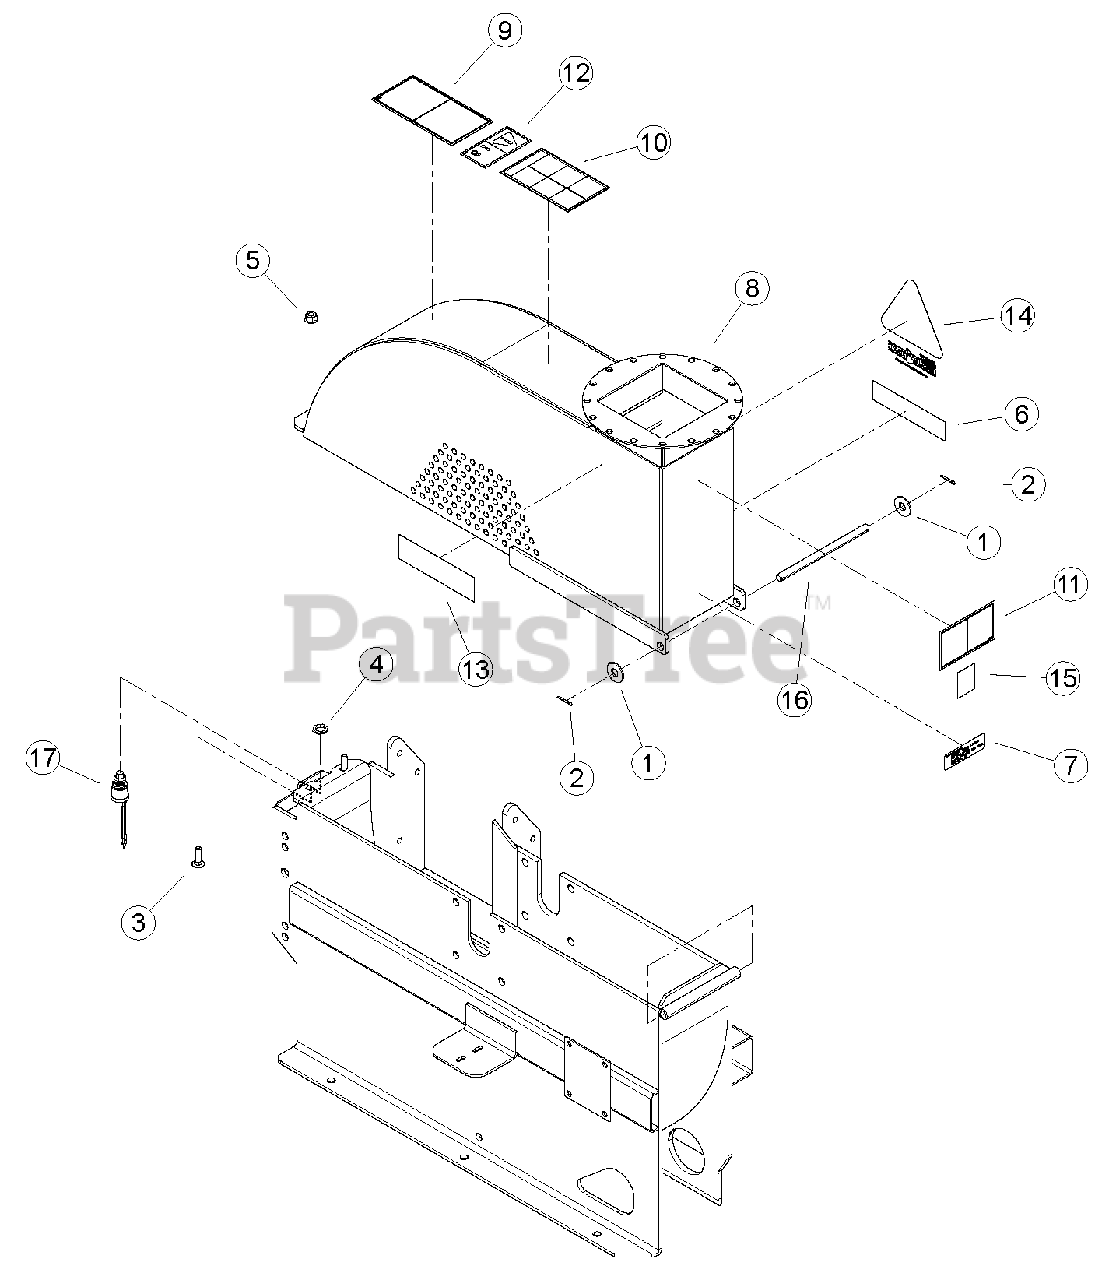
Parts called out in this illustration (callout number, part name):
1	WASHER, 1/2" FLAT ZP
2	PIN, 1/8 X 1.00 ZP COTTER
3	BOLT, 3/8 X 1-1/4" GR5 CRG NC ZP
4	NUT, 5/8-32 JAM
5	NUT, 3/8-16 NYLOCK FLANGE
6	DECAL, MODEL CH8720IH
7	DECAL, ATLANTIC BRIDGE LTD INFO (CE COMPLIANT ONLY)
8	ASSEMBLY, CHIPPER COVER W/DECALS
9	DECAL, KNIFE ACCESS ISO
10	DECAL, OPERATING INSTRUCTIONS ISO
11	DECAL, DISCHARGE ISO
12	DECAL, MAINTENANCE ISO
13	DECAL, ECHO BEARCAT 6.82 X 1.90
14	DECAL, CHIP IT
15	DECAL, ECHO BEARCAT QR CODE
16	SHAFT CHIPPER TOP PIVOT
17	ASSEMBLY, SEALED SWITCH
